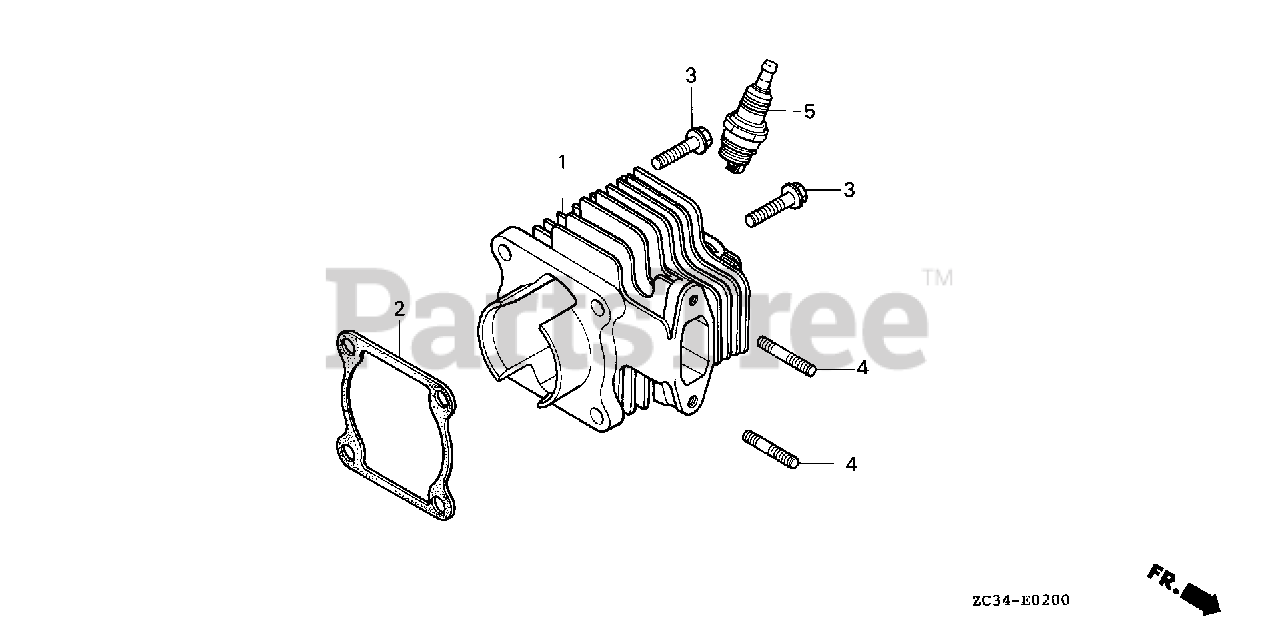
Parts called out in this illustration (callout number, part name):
2	GASKET, CYLINDER
3	BOLT, FLANGE (6X20)
4	BOLT, STUD (5X16)
5	SPARK PLUG (BMR6A) (NGK)
